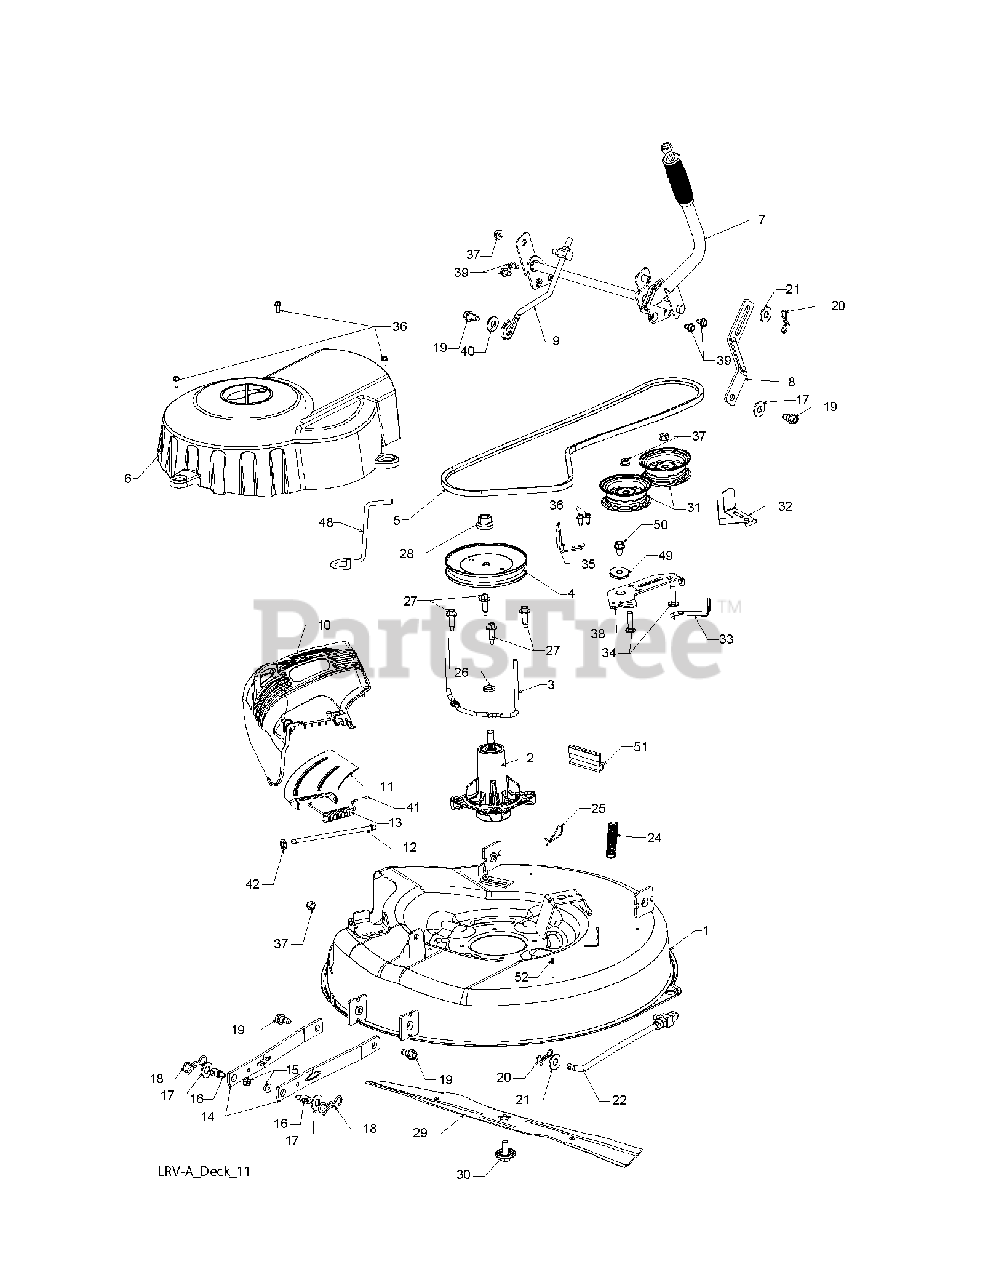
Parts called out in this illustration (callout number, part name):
1	DECK, 26"
2	MANDREL.ASM.SUB-NON.GR
3	KEEPER.BELT.MANDREL.PULLEY
4	PULLEY.MANDREL
6	COVER, MANDREL
7	SVC.LIFT.ASM.LRVA
8	LINK, DECK LIFT
9	LINK.ASM.LIFT.ADJUSTABLE
11	SUPPORT, DEFLECTOR
12	ROD.HINGE
13	SPRING.TORSION.DEFLECT
14	ARMS.SUSP.MOWER.REAR.SRD
15	NUT LOCK HEX FLANGE 5/16-18
16	STUD.FASTNER.W/ANTI-ROTATE
17	WASHER.CLEAR.ZINC
18	PIN.COTTER.7/16.BOW TI.
19	BOLT.SHOULDER
20	PIN.COTTER.5/16.BOW TI
22	LINK.ASM.TOP.DECK.LRV
23	NUT LOCK FLG 3/8-16 UNC
24	SPRING.EXTENSION.DECK.LRV
26	WASHER.SPACER.MANDREL
27	SCREW, WASHER HEAD
28	NUT.FLANGE.LOCK.TOP
29	BLADE.26"
30	BOLT.WASHER.ASM.7/16-2
31	PULLEY.IDLER.48"PRIMARY
32	GUARD, BELT
33	KEEPER BELT
34	BOLT.3/8-16X1.50
35	ARM BRAKE MOWER RH
36	SCREW.1/4-20X5/8
37	NUT LOCK FLG 3/8-16 UNC
38	ARM, IDLER
39	SCREW LT
41	CAP-SLEEVE LT
42	NUT PUSH M
48	KEEPER.BELT
49	SPACER.RETAINER
50	SCREW 3/8-16X1
51	BUMPER.HOOD.TEX.HUSQVARNA
52	SCREW 3/8-16X1/2
